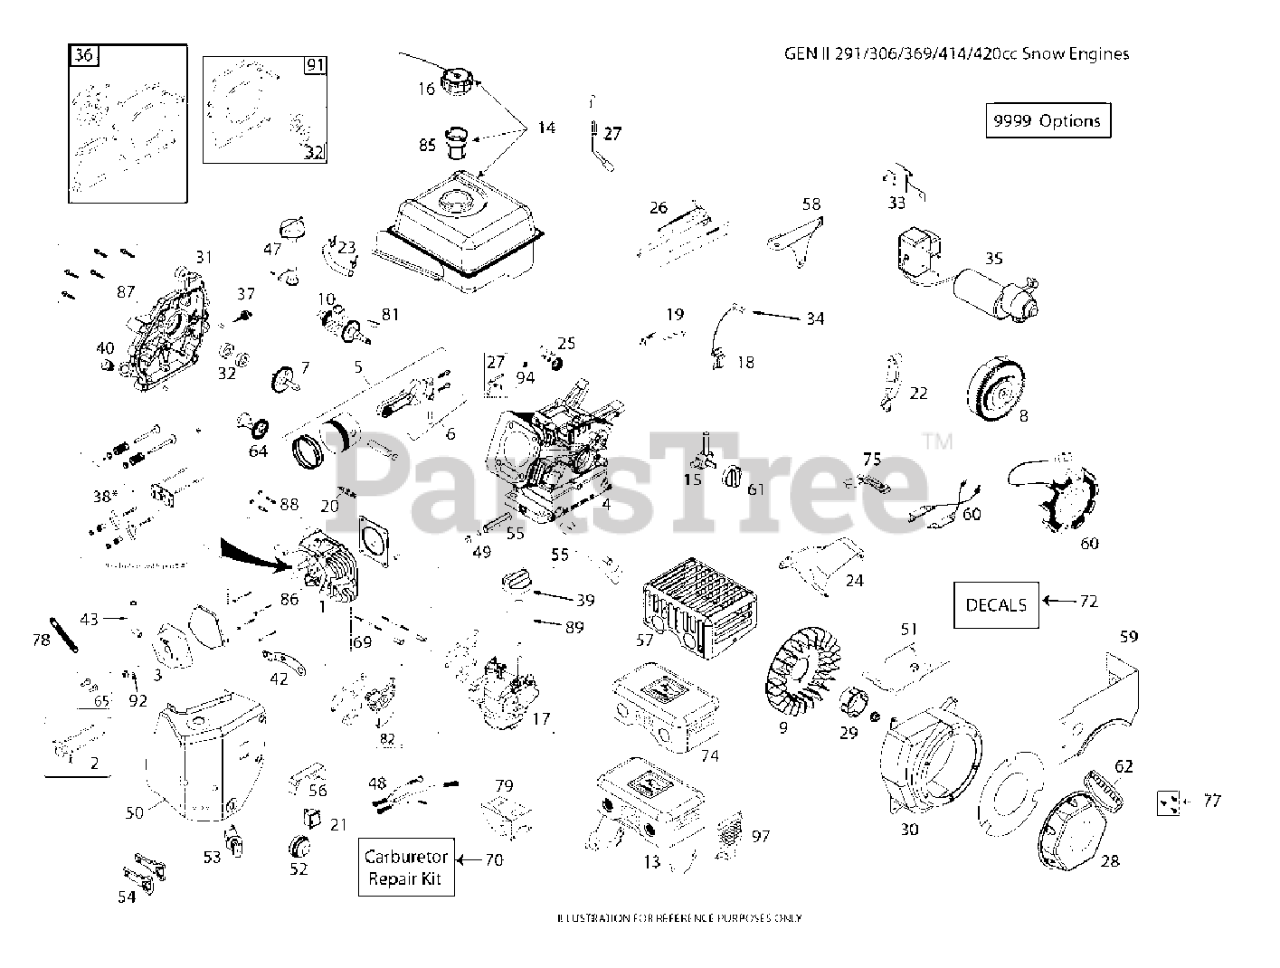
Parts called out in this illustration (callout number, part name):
1	CYLINDER.HEAD.ASSY(SK2911000)
2	PUSH ROD TAPPET KIT
3	VALVE.COVER.LCT.414CC.
4	CYLINDER.ASSEM.291CC.LCT.SNOW
5	PISTON.AND.ROD.ASSY(SK2911400)
6	CONNECTING ROD ASSY SNO.LCT
7	CAMSHAFT.LCT.291CC
8	FLYWHL.ASSY.ELECT.(SK2911701)
9	FLYWHEEL.FAN
10	CRANKSHAFT.KEYED.SNOW.291CC.LC
13	MUFFLER.ASSY.SNOW(SKSN4200)
14	FUEL TANK ASSY - SNOW (291CC)
15	FUEL.PETCOCK.SNOW(SKSN4900)
16	FUEL.TANK.CAP.SNOW(SKSN4301)
17	CARBURETOR.ASSY.SNOW(SKSN2302)
18	IGNITION COIL ASSY
19	CDI.BOX.ASSY.SNOW(SKSN4404)
20	SPARK.PLUG(SK2911550)
21	ON/OFF.SWITCH.SNOW(SKSN4403)
23	FUEL HOSE KIT
24	TOP.SHIELD.LCT.
25	GOVERNOR.GEAR.ASSY(SK2912900)
26	GOVERNOR.ARM.ASSY.(SKSN2502)
27	GOVERNOR.SHAFT.(SK2913100)
28	RECOIL.START.ASSY.(SKSN2600)
29	STARTER.CUP.SMALLSNOW(SKSN2601
30	HOUSING.BLOWER.ASM
31	CRANKCASE.COVER.ASY(SK2913600)
32	OIL.SEAL.KIT(SK2913900)
33	SWITCHBOX BRACKET ES LCT 291 S
34	SPARK.PLUG.BOOT.SNW,SKSN4691.1
35	ELECTRIC.START.ASSY(SKSN2400.2
36	ENGINE.GASKET.KIT(SK2914300)
37	DIPSTK.OIL.BLK.LCTSK4143711.1
38	ROCKER ARM KIT
39	CHOKE.KNOW.SNOW(SKSN4500)
40	NONREMVABLE.OIL.PLUG(SK4143715
42	CDI.BOX.BRKT.SNOW(SKSN4402)
43	TUBE.BREATHER.LCT.219CC/414CC
47	HIGHOIL.FILL.ASSY.KIT(SKSN4911
48	WIRE.HARNESS(SKSN4406)
49	OIL.DRAIN.PLUG
50	HEATER.BOX.ASSY.SNOW(SKSN2100)
51	SHIELD.CYLINDER.SNOW(SK4141010
52	PRIMER.BULB.ASSY(SKSN4304)
53	KEY.SWITCH.ASSY.SNOW(SKSN4401)
54	KEY SET(2 KEYS) SKSN0407.1
55	EXTENDED OIL DRAIN TUBE
56	SHIELD.VAPOR(SKSN4606)
57	SHIELD.MUFFLER.
58	GOVERNOR.LINK.SHIELD(SKSN2501)
59	FUEL.TANK.SKIRT(SKSN2101)
60	CHARGING.COIL.AC/DC(SK4141710)
61	FUEL KNOB-SNOW
62	STARTER.GRIP.SNOW(SKSN2603.1)
65	TAPPET KIT.LCT.SK2911005.1
69	STUD.CARB.MOUTING.KIT.291CC
70	CARBURETTOR REPAIR KIT 291CC/4
77	BOLT.KIT.RECOIL.LCT.ALL.ENGINE
81	KEYS.FLYWHEEL.136/291CC.5PACK
82	SPACER.CARBURETOR.291CC.LCT
85	STRAINER.FUEL.TANK.LCT.208CC
86	KIT.BOLT.CYLINDER.HEAD.(4PC)
87	KIT.7-BOLT.CRANKCASE.CVR.291CC
88	STUD.MUFFLER.KIT.LCT
91	GASKET KIT CRANKSHAFT.LCT
92	CENTER VALVE COVER BOLT
97	GUARD.EXHAUST
9999	STARTER SCREW.STARTER SWITCH B
9999	HIGH.ALTITUDE.JET.6000FT ANDUP
9999	KIT.BOLT.LCT.SK9990.1
